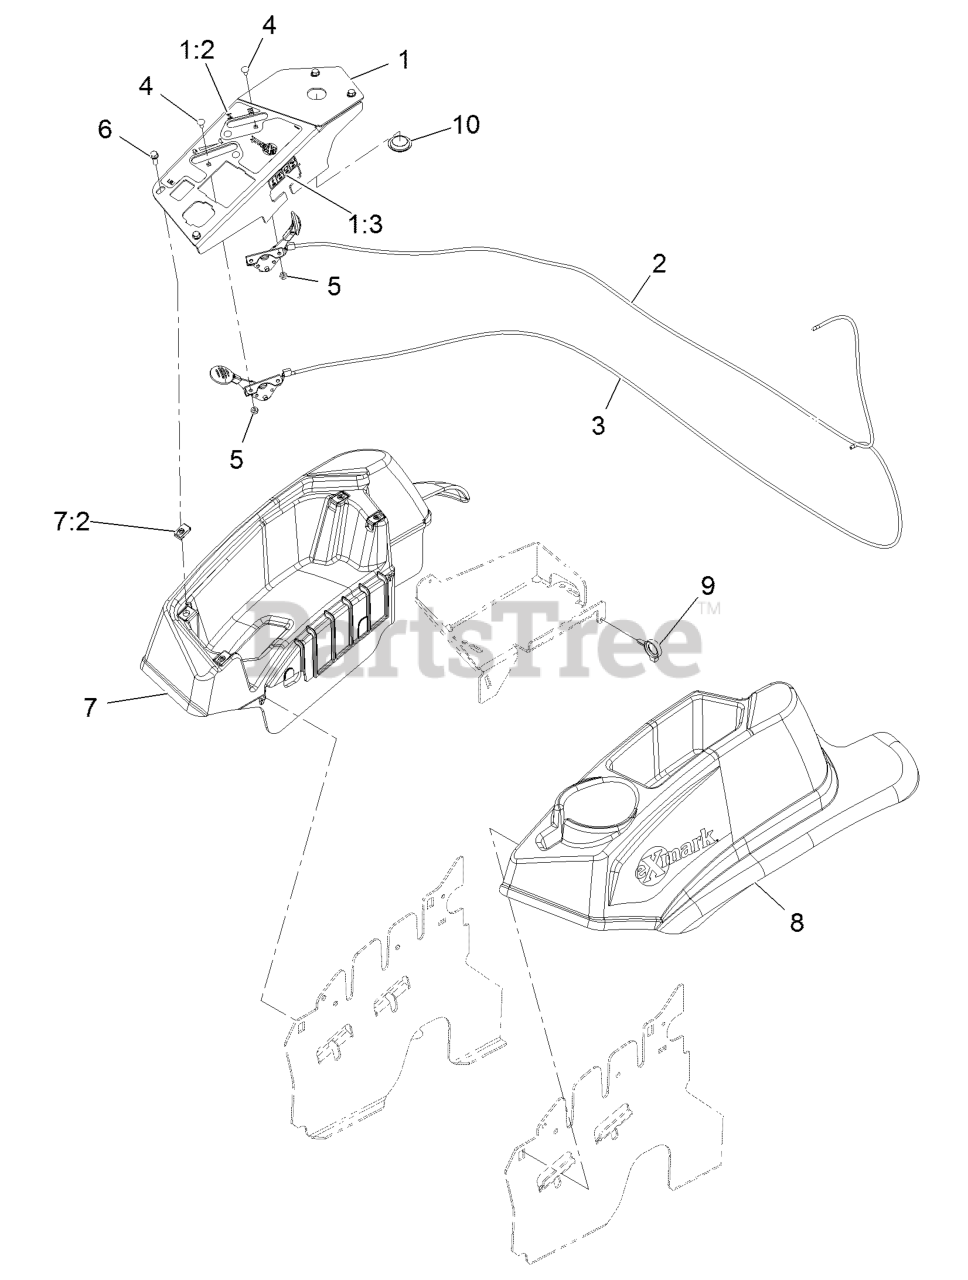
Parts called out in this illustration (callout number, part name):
1	CONSOLE,PANEL W/DECAL
1:2	DECAL-CONTROL PANEL NON-E
1:3	DECAL-FUSES
2	ASM, CHOKE CABLE
3	ASM,THROTTLE CABLE
4	BOLT-CARR
5	NUT-LOCK, NI
6	SCREW-HWH
7	CONSOLE,RH AS ASM
7:2	Nut-Retainer-Panel 1/4-20
8	CONSOLE, LH AS
9	CLAMP-HOSE
10	PLUG-PLASTIC
